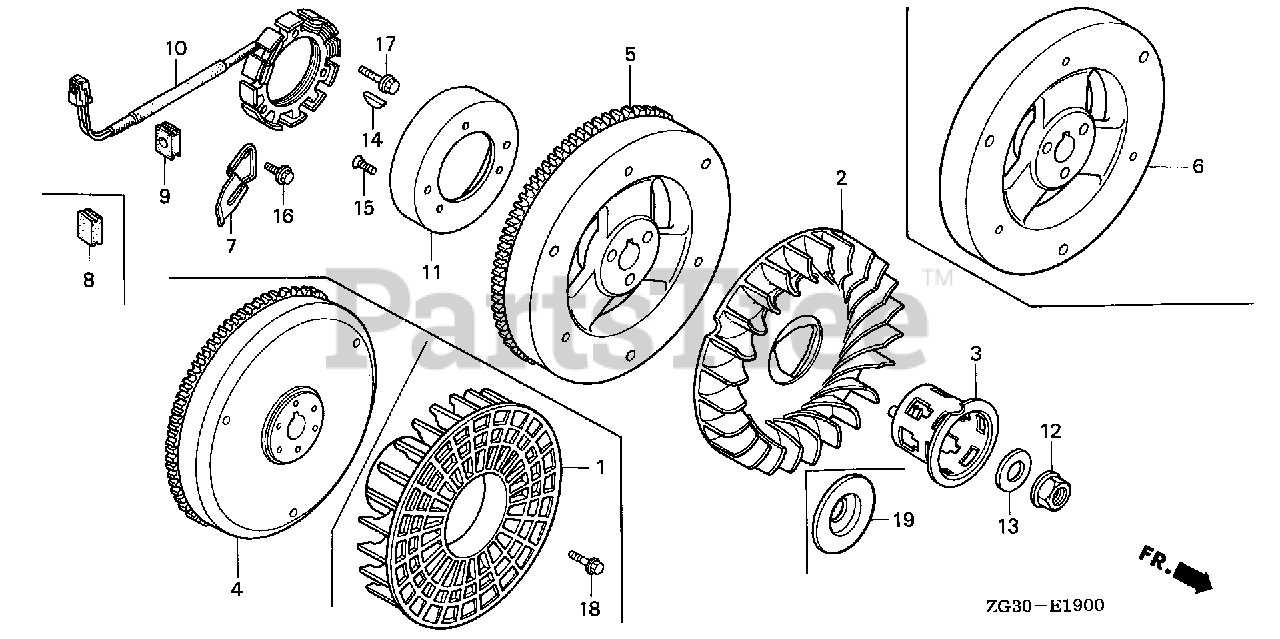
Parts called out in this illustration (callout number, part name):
2	FAN, COOLING
3	PULLEY, STARTER
5	FLYWHEEL (SEL)
7	CLAMP, WIRE
9	GROMMET, WIRE
10	STATOR (1.7A)
11	ROTOR (4MAGNET)
12	NUT, FLANGE (20MM)
13	WASHER (20MM)
14	KEY, WOODRUFF (50X7)
15	SCREW, FLAT (6X12)
16	BOLT, FLANGE (6X12)
17	BOLT, FLANGE (6X22)
